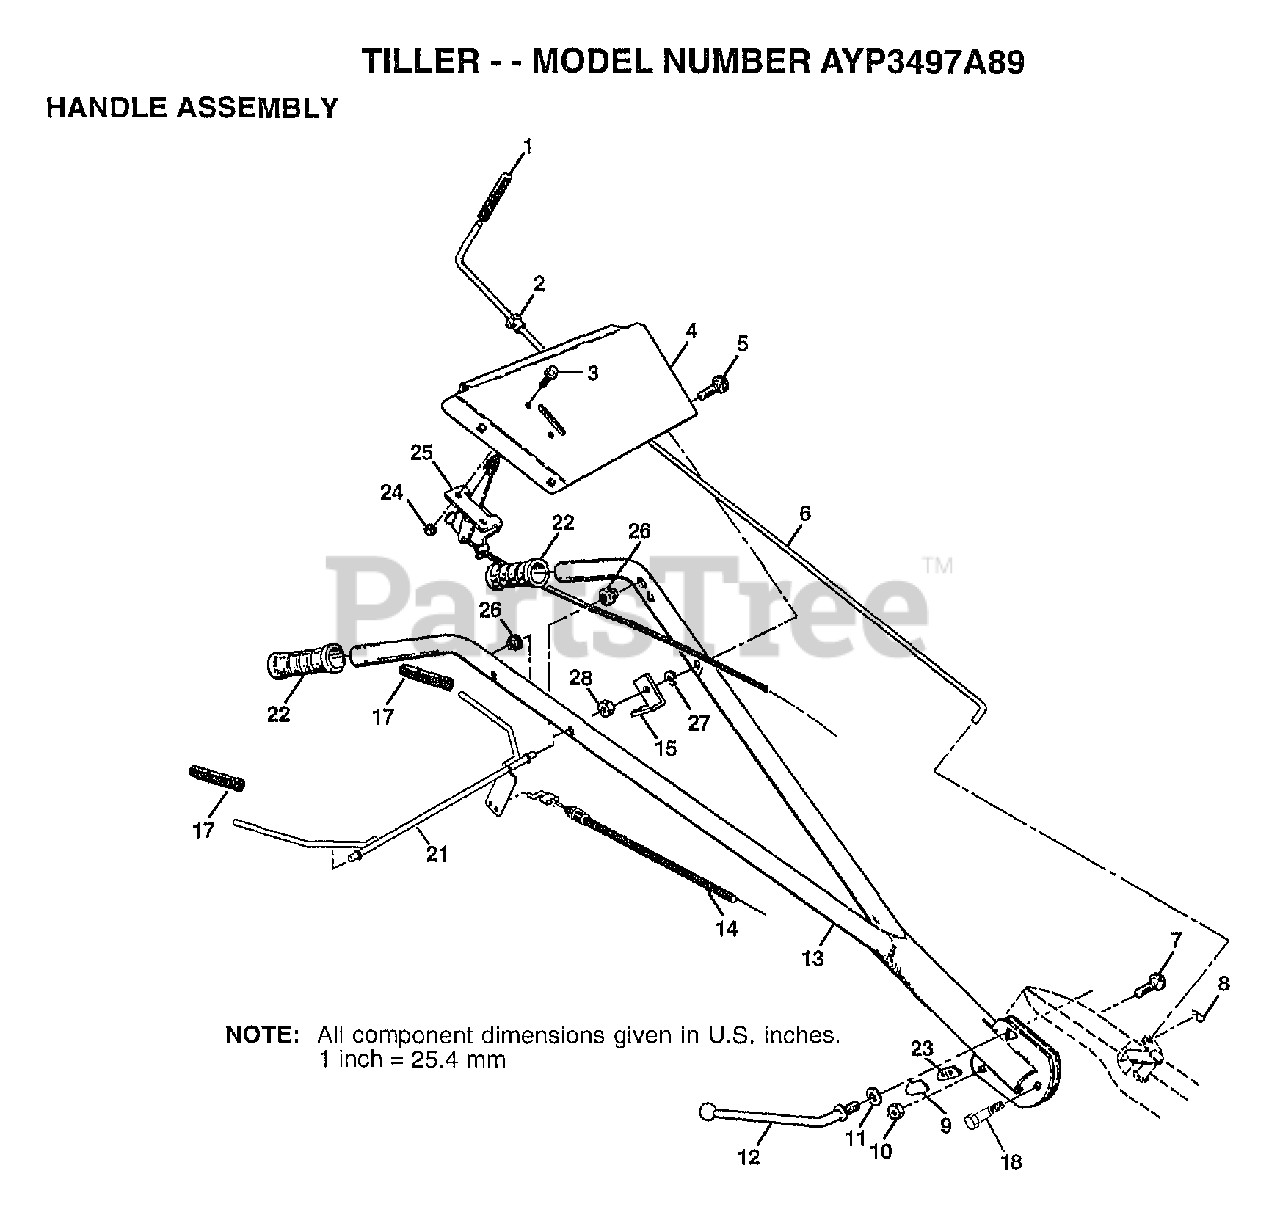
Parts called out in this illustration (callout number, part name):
1	GRIP TI
2	BUSHING
3	SCREW.PNHD.10-24
4	HANDLE BRACKET
5	BOLT CARRIAGE CRT
6	ROD SHIFT CRT
7	BOLT D
8	RETAINER M
9	LOCK CRT
10	LOCKNUT
11	WASHER CRT
12	LEVER LOCK CRT
14	CABLE.CLUTCH.Z-BE
15	BRACKET.CLUTCH.CA
17	GRIP BAR CRT
18	BOLT PIVOT
21	BAR CONTROL
22	"GRIP,HANDLE"
23	LOCK.HANDLE
25	CONTROL.THROTTLE
26	GROMMET.HANDLE.V-
27	LOCKWASHER
28	NUT
